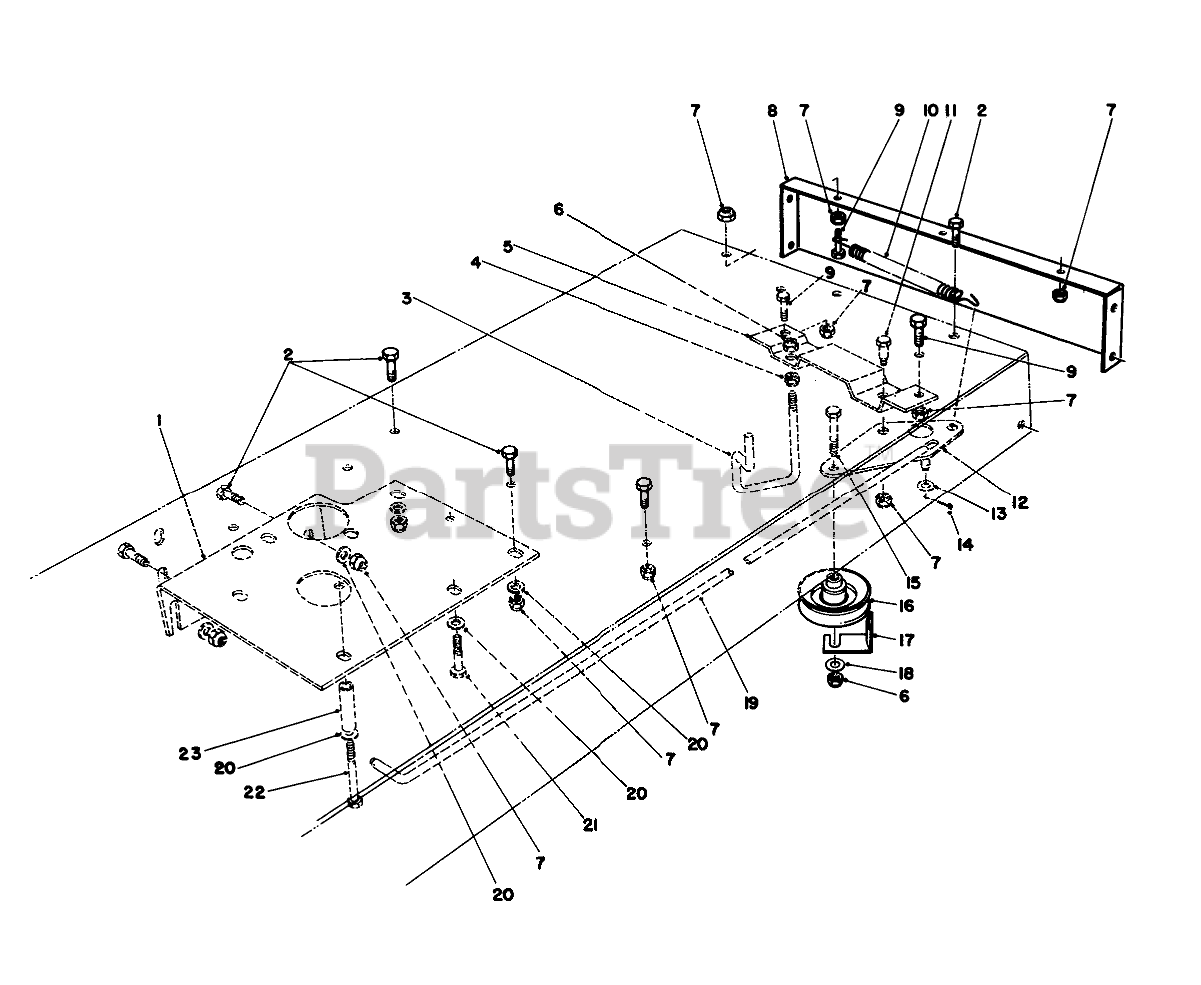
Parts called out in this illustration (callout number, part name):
1	REINF PLATE R
2	SCREW-HH
3	BELT GUIDE
4	NUT-LOCK, SIDE
5	TRACT SUPP BRKT B
6	NUT-LOCK, CONE
7	NUT-LOCK, NI
8	REAR FRAME R
9	SCREW-HH
10	TRACTION SPRING
11	BOLT-SHOULDER
12	Bracket-Traction Pivot
13	WASHER-FLAT
14	PIN-COTTER
15	SCREW-HH
16	PULLEY-IDLER
17	RETAINER-BELT
18	WASHER-FLAT
19	TRACTION ROD
20	WASHER-PLAIN
21	Screw-HH
22	SCREW-HH
23	OUTER TUBE SPACER
